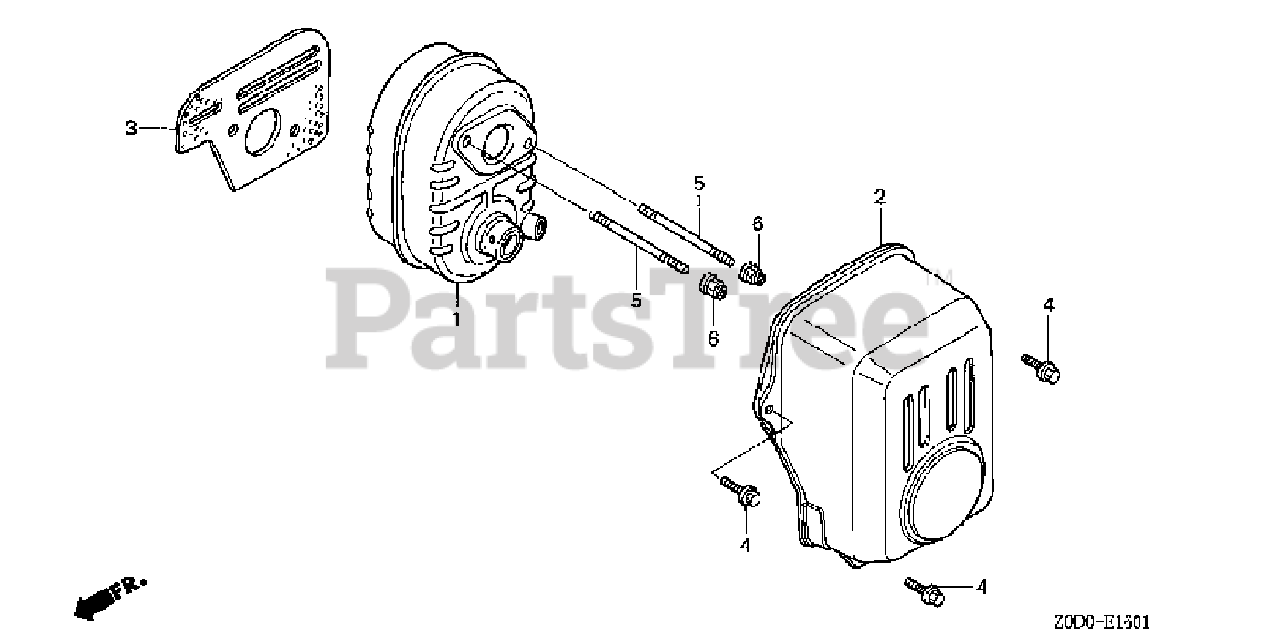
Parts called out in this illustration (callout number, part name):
1	MUFFLER
2	PROTECTOR, MUFFLER
3	GASKET, MUFFLER
4	BOLT, FLANGE (6X14)
5	BOLT, STUD (6X78) (CT200)
6	NUT, SELF-LOCK (6MM)
